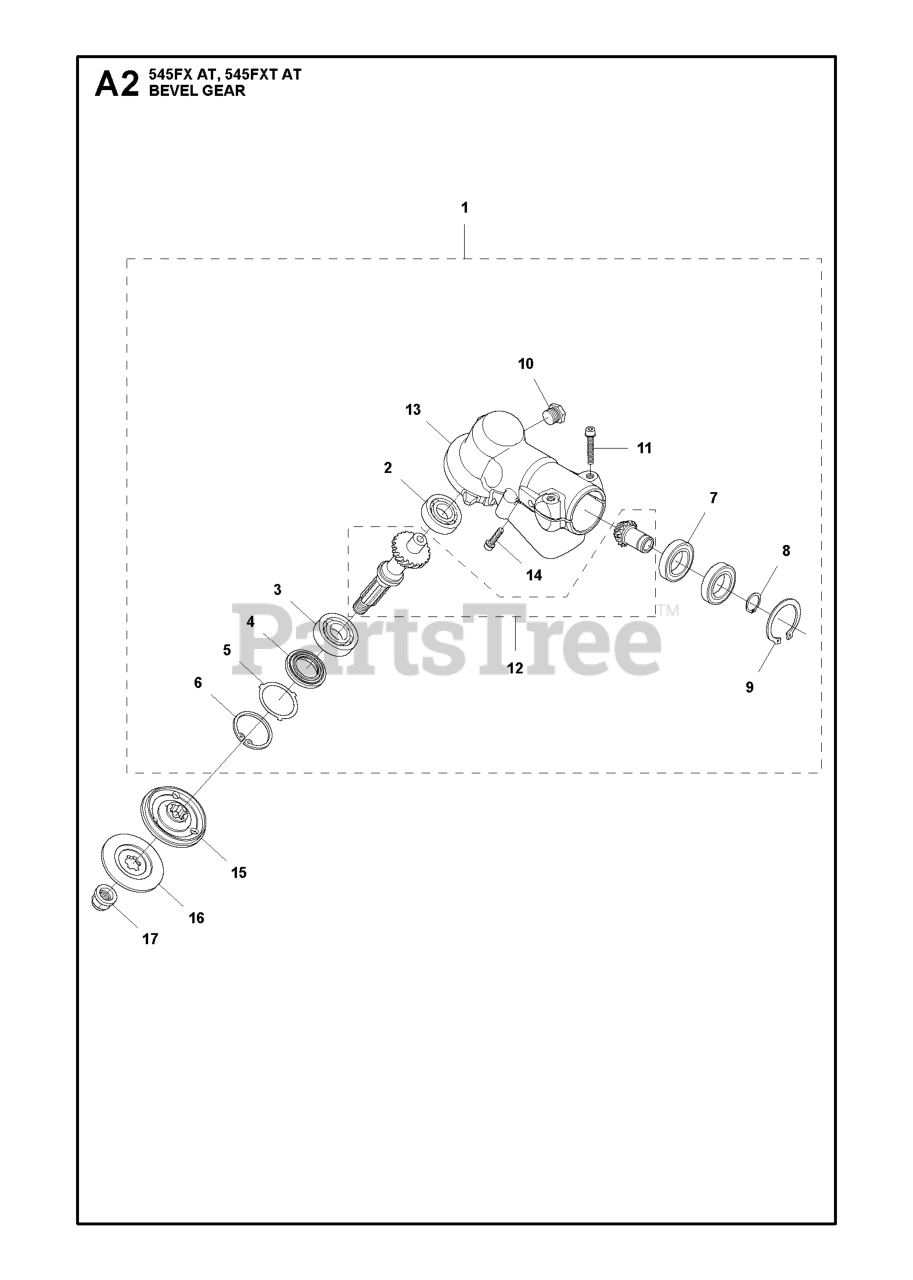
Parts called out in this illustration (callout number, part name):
1	NUT 1/2-13 HEX NYLOC ZD
5	SUPPORT BRACKET
6	NUT 3/8-16 NYLOC
7	HCS 3/8-16X1.GRD.5.ZD
8	HCS 1/2C X 1 1/4 SERRATED HEAD
